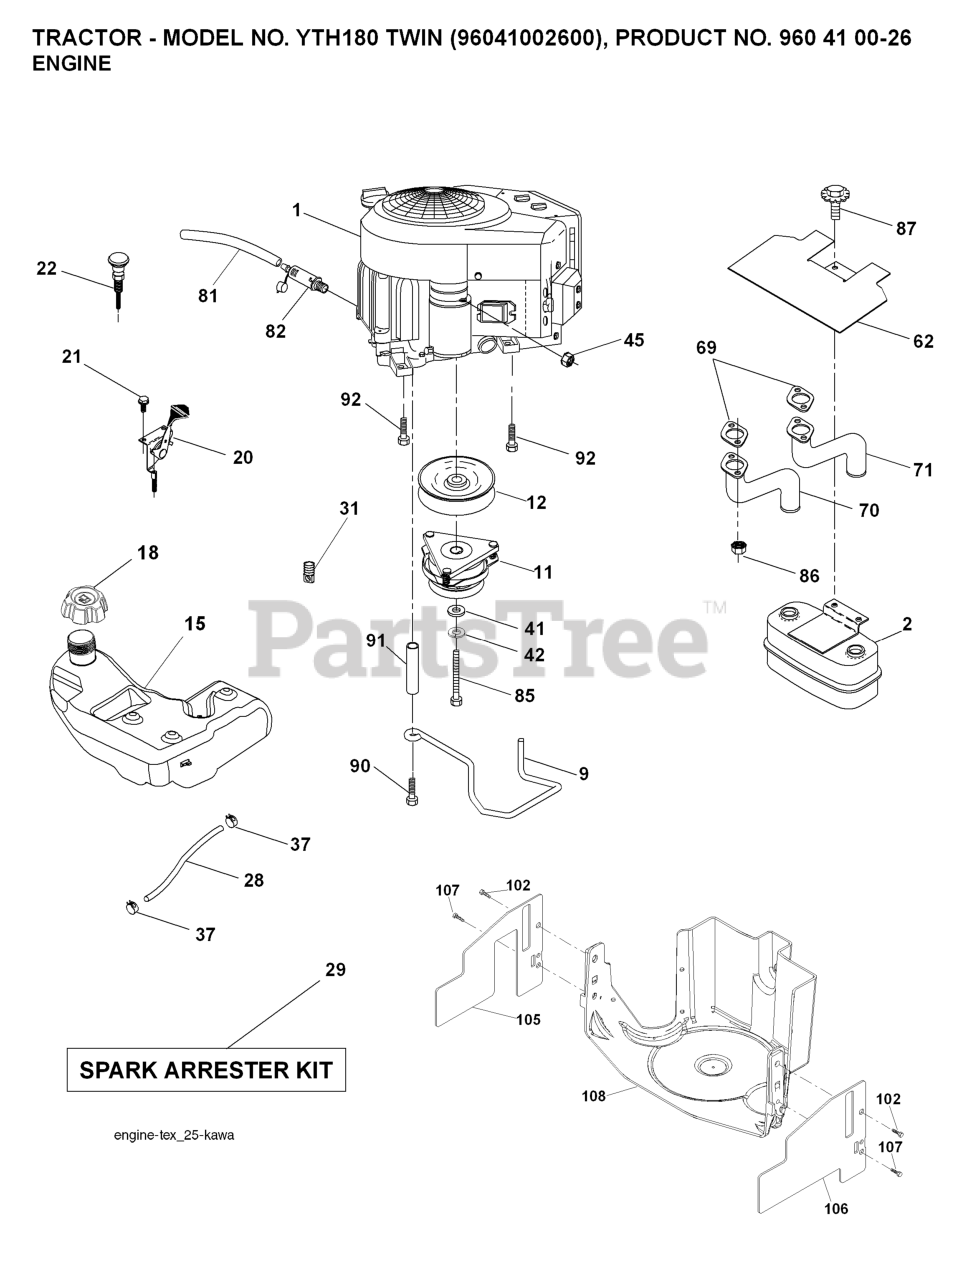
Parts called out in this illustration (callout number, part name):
2	MUFFLER.TWIN.CYL.LOW.TONE
9	KEEPER.BELT.ENGINE.3.25 (3 2)
11	RB.CLUTCH.OGURA.4.4.PD
12	PULLEY.ASM.ENG.OGURA.3
15	TANK.FUEL.4GAL
18	CAP.FUEL.TANK.3"GREY
20	THROTTLE CONTROL
21	SCREW
22	CONTROL, CHOKE
28	REPL BY 532 00 85-43
29	KIT.SPARK ARRESTOR 794945 B&S
37	HOSE CLAMP
42	LOCKWASHER
45	NUT
62	RP SHIELD HEAT MUFFLER
70	EXHAUST.TUBE.LH.KAWASAKI.
71	EXHAUST.TUBE.RH.KAWASAKI.
81	TUBE, DRAIN OIL ASM.
82	PLUG DRAIN OIL EASY
85	BOLT HEX 7/16-20X4-1/4"
86	NUT.HEX.FLANGE.TOPLOCK
87	BOLT.5/16-18UNCX1.W/SEMS.BLK
90	SCREW 3/8-16X1
91	BUSHING.1.375OD
92	SCREW 3/8-16X1
102	SCREW
105	SHIELD.SIDE.LH.3842"TEX FRENCH
106	SHIELD.SIDE.RH.3842"TEX FRENCH
107	SCREW.1/4-20X5/8
